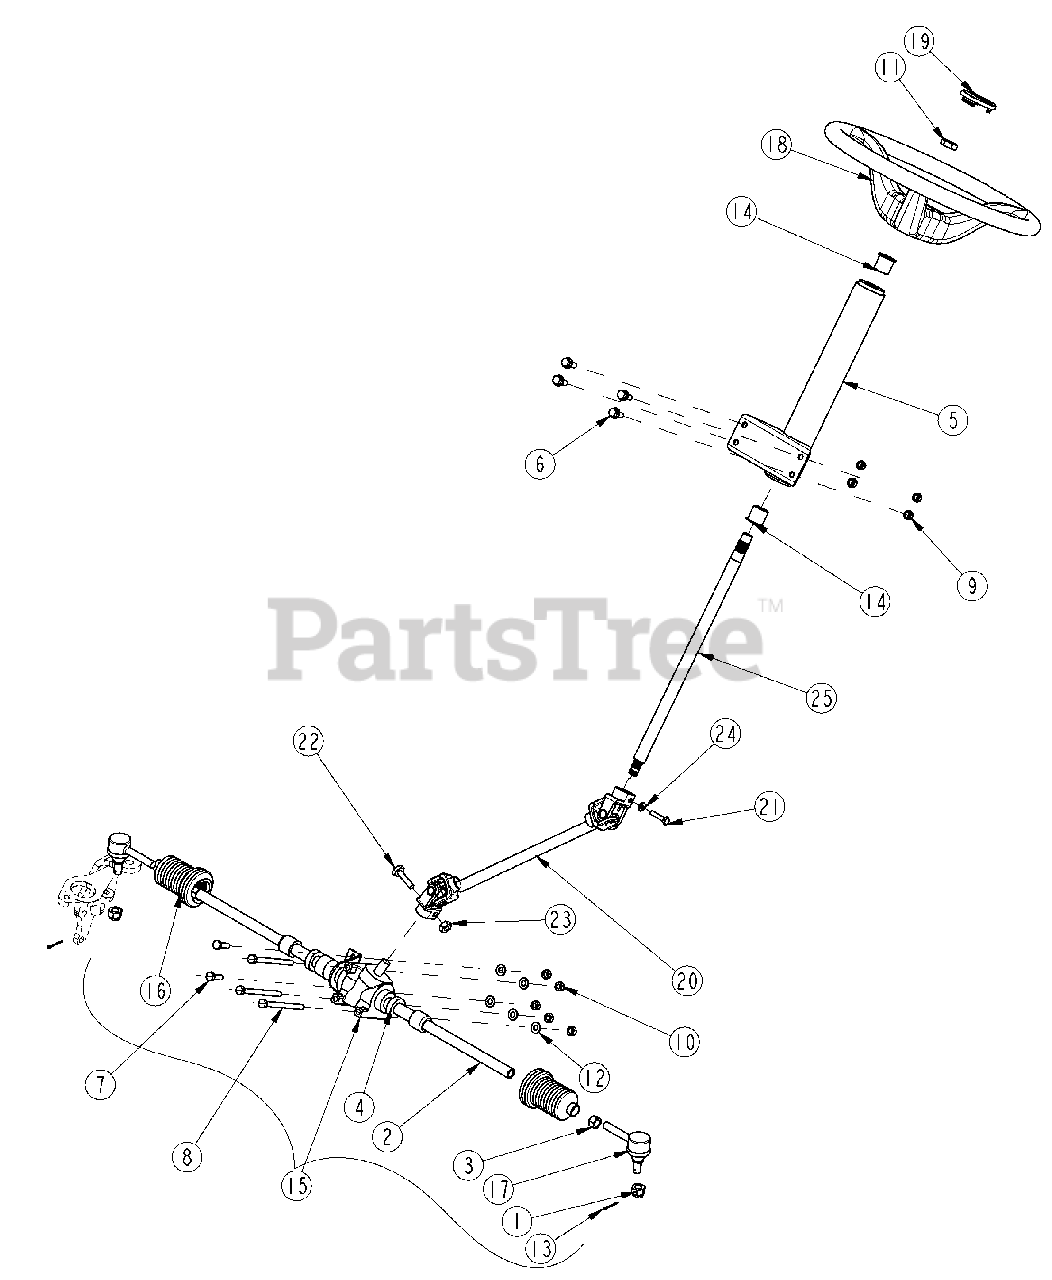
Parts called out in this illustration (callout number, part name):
1	NUT HEX SLOTTED M12X1.25 PLT
2	TIE ROD W/BALL 826-399C/400C
3	NUT HEX M14X1.5 PLT
4	SPACER 826-399C/400C
5	STEERING COLUMN WELDMENT
6	HFS 5/16-18X3/4 GR5
7	HHCS M8X1.25X25 GR8.8 YLW PLT
8	HHCS M8X1.25X100 GR8.8 PLT
9	NUT HEX NYLOCK 5/16-18 PLT
10	NUT HEX NYLOCK M8X1.25 PLT
11	NUT HEX M16X2.00X8MM THK PLT
12	WASHER FLAT 5/16 HARD ASTMF436
13	PIN COTTER 3/32 X 1 LONG
14	BUSHING 1 OD X .75ID X 1
15	RACK & PINION ST
16	BOOT 826-399C/400C
17	TIE ROD
18	STEERING WHEEL
19	CAP 2 ID PLASTIC (BDY/STRG WHL
20	STEERING SHAFT TRUCK
21	MVL BOLT FOR 840-093C
22	HHCS M10X1.5X35 PLT
23	NUT HEX NYLOCK M10X1.5 PLT
24	MVL SPRING WASHER FOR 840-093C
25	UPPER STEERING SHAFT TRUCK ASM
